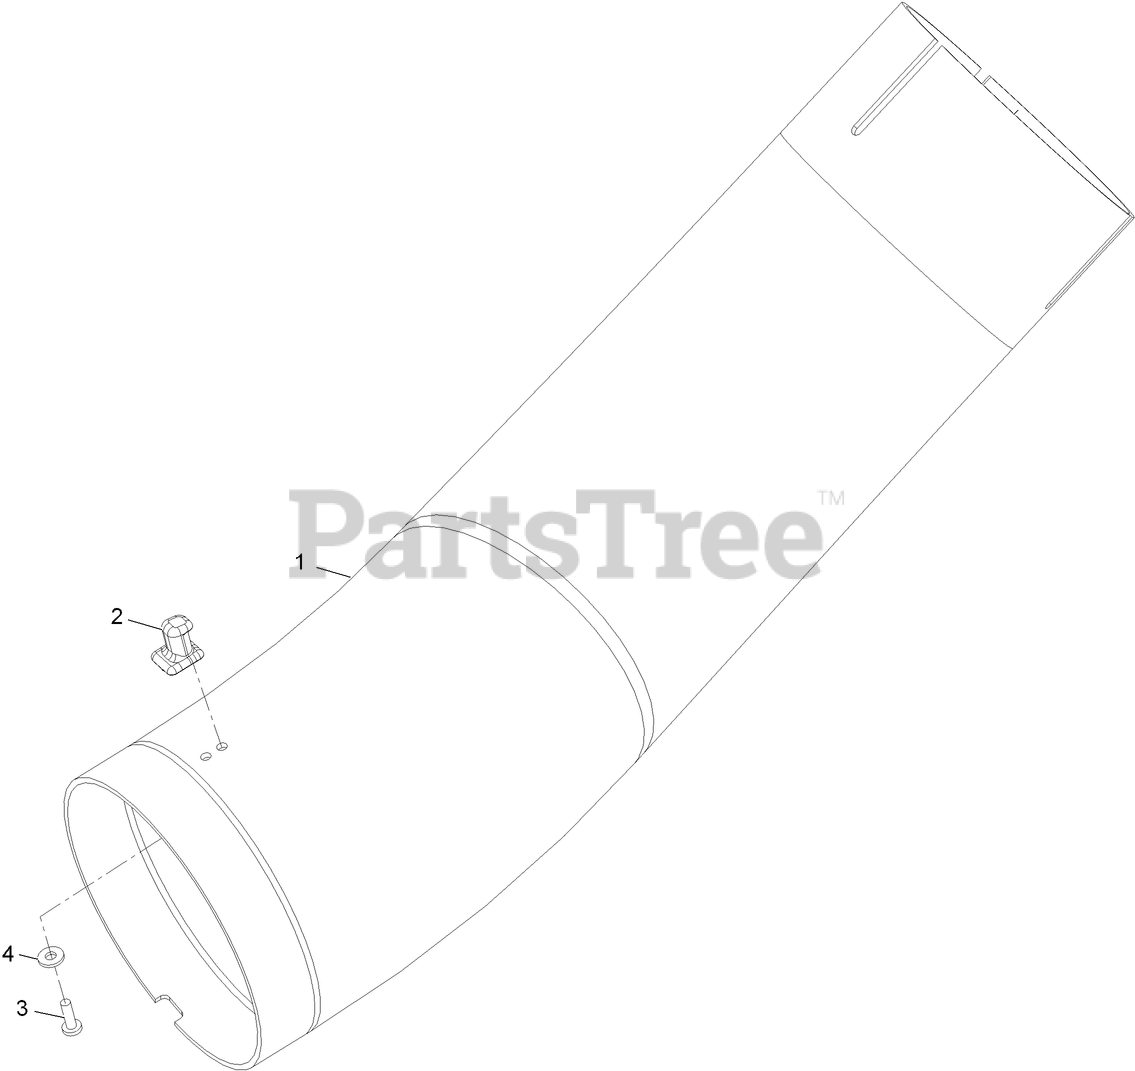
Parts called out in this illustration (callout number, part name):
1	Tube, Lower Short
2	LATCH-KEEPER
3	SCREW-PPH
4	WASHER-FLAT
